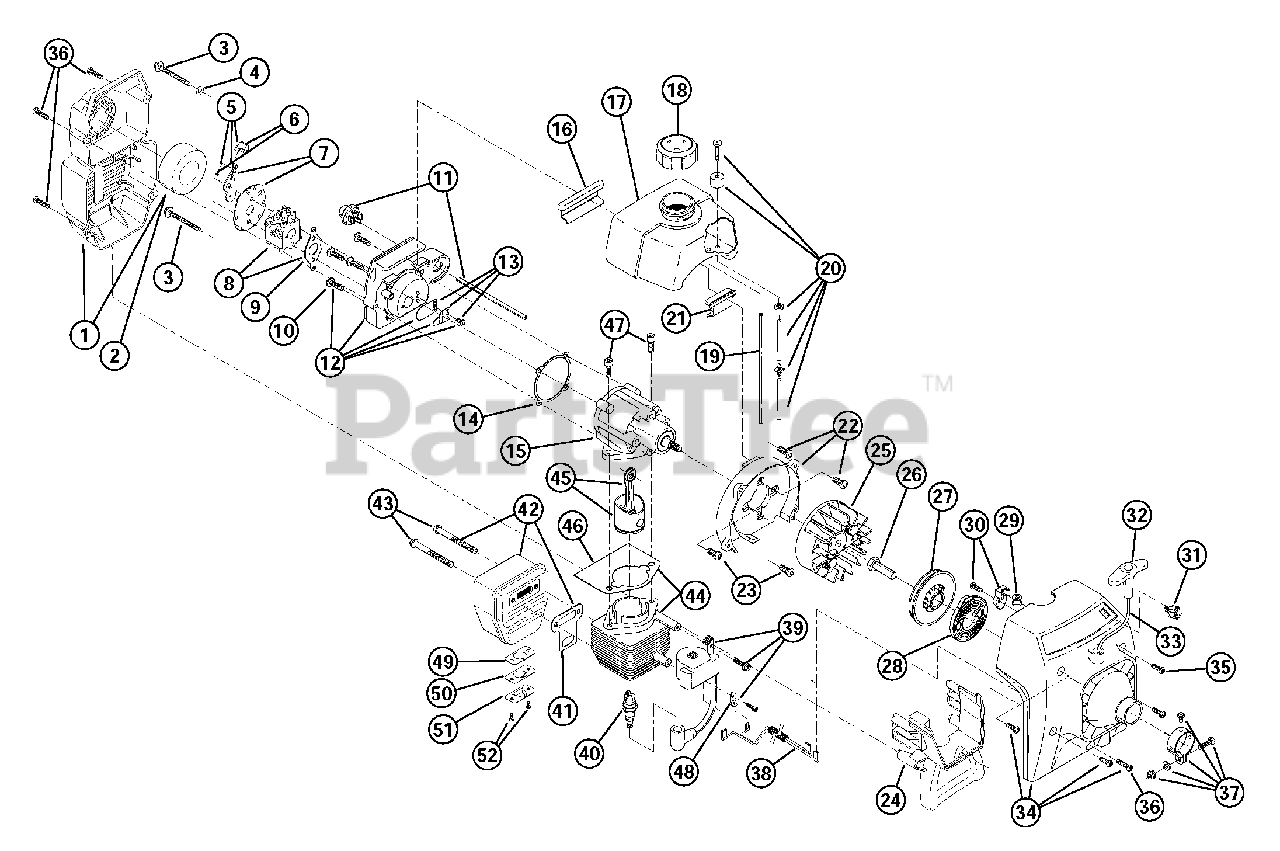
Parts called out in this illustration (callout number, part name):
1	Air Cleaner/Muffler Cover Assembly
2	Air Cleaner Filter
3	Carburetor Mounting Screw Assembly
4	Wavey Washer
5	Choke Lever Assembly
6	Choke Knob and Screw
7	Choke Lever and Plate
8	Carburetor Assembly
9	Carburetor Gasket
10	Carb Mount Screw
11	Primer and Hose Assembly
12	Carb Mount Assembly
13	Reed Assembly
14	Carburetor Mount Gasket
15	Crank Case Service Assembly
16	Rear Mounting Pad
17	Fuel Tank Assembly
18	Fuel Cap Assembly
19	Fuel Return Line
20	Fuel Line Assembly
21	Front Mounting Pad
22	Shroud Assembly
23	Shroud Screw
24	Shroud Extension and Stand
25	Flywheel Assembly
26	Square Nut Drive
27	Recoil Pulley Assembly
28	Recoil Spring
29	Rope Guide
30	Pulley Retainer Assembly
31	Switch Assembly
32	Pull Handle
34	Starter Housing Assembly
35	Housing Screw
36	Cover Screw
37	Upper Clamp Assembly
38	Wire Lead
39	Module Assembly
40	Spark Plug
41	Exhaust Gasket
42	Muffler Assembly
43	Muffler Mounting Bolt Assembly
44	Cylinder Assembly
45	Piston and Rod Assembly
46	Cylinder Gasket
47	Cylinder Bolt
48	Ground Tab
49	Spark Arrestor Screen
50	Inner Hood
51	Hood
52	Screw
